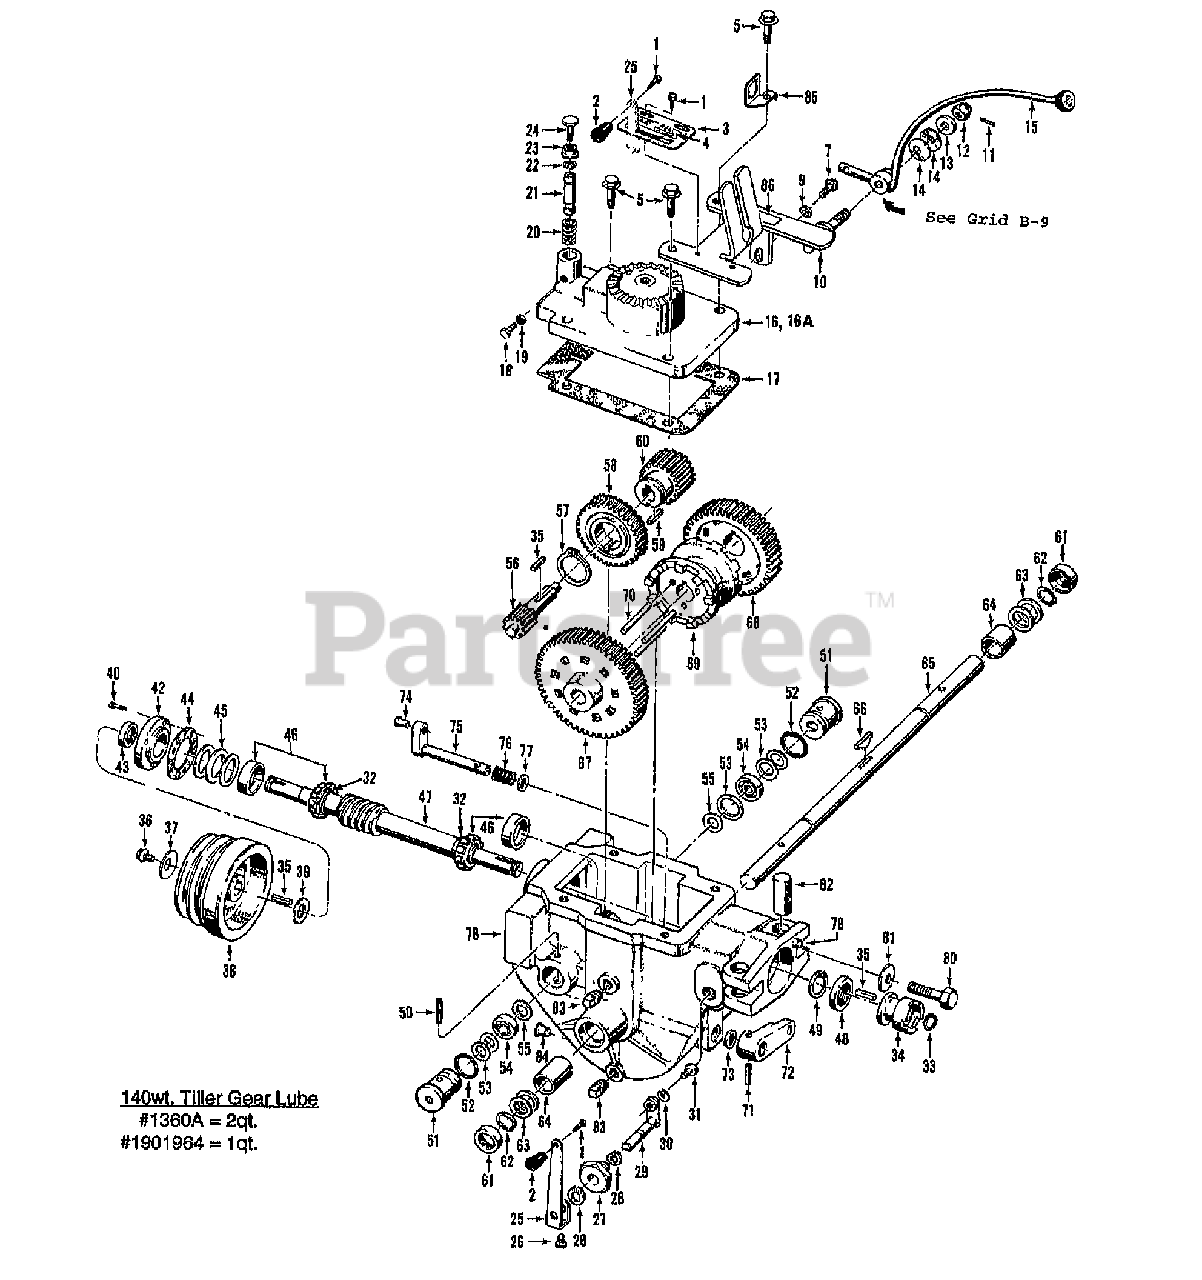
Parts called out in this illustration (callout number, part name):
1	SCR 10-32
2	KNOB-TAPERED
3	PLATE-TINE ENGAGE W/DECAL
4	DECAL-TINE ENGAGE
5	SCR-HFLK 3/8-16X1.50
6	THIS REF. NO. NOT USED
7	SCR-HFLK 5/16-18X.75 ZP
8	THIS REF. NO. NOT USED
9	WASHER-FLAT 5/16 SAE
10	BRKT-H HOOD 2149
11	PIN-SPRING .125 X 1
12	NUT-HEX 1/2-20
13	WASHER-# SHOULDER ZP
14	WASHER-# 1.97X1X.118
15	THIS REF. NO. NOT USED
16	COVER-TRANS RED 2523
16A	ASSM-TRANS COVER OPC
17	GASKET-TRANS COVER
18	SCR-HH 5/16-18X1.0 G5 ZP
19	NUT-HEX 5/16-18 ZP
20	SPRING-REV PLUNGER ZP
21	ASSM-NEUTRAL PLUNGER
22	RING-KLIP EXT .594 ID ZP
23	NUT-HFLK 3/8-16 ZP
24	SCR 3/8-16X1.5 UNC-2AG
25	LEVER-ECCENTRIC RED
26	SCR-HH 1/4-20X.5 GR5 YEL
27	BUSHING-.87X.5X.62 ECC
28	RING-RETAINING 5100-50
29	SHAFT-WELD ECCENTRIC
30	WASHER-LK .25 HI-COLLAR
31	SCR-HXSKT 1/4-20X.38 G8
32	SHIM-1.0X.7656X.062
33	RING-RETAIN EXT .707 ID
34	KIT-CLUTCH DOGS TILLER
34	CLUTCH-DOG HORSE TRANS
35	KEY-.188 SQX1.0
36	SCR-HH 5/16-24X.75 G5 ZP
37	WASHER-.827X.331X.098
38	PULLEY-TRANS MACH
39	WASHER-SHLDR HARDENED
40	SCR-HFLK 1/4-20X.75 G5 ZP
41	THIS REF. NO. NOT USED
42	COVER-FRONT
43	SEAL-PINION SHAFT PT/85030/00
44	GASKET-BRG COVER
45	SHIM-1.75X1.5X.01
45	SHIM-1.75X1.5X.03
45	SHIM-1.75X1.5X.005
45	SHIM-1.75X1.5X.062
46	KIT-BRG CONE&RACE-DRIVESHAFT
47	KIT-WHEELDRIVE ROLL/WORM
48	SEAL-OIL DRIVESHAFT
49	RING-RETAINING 5000-181
50	PIN-SPIROL .25 X 2.0
51	PLUG-PINION BRG W/RING
52	RING-O 1 ID
53	SHIM-1.234X1.015X.033
53	SHIM-1.234X1.015X.062
53	SHIM-1.234X1.015X.01
54	BRG-BALL (7 BALLS)
55	WASHER-# 1X.484X.06
56	GEAR-SPLINE 10 TEETH MACH
57	RING-RETAINING 5100-150
58	GEAR-WORM MACH
59	KEY
60	GEAR-SPUR 20 TEETH MACH
61	SEAL-OIL WHEELSHAFT
62	RING-HEAVY EXT .906 ID
63	SHIM-1.375X1.015X.062
63	SHIM-1.375X1.015X.03
63	SHIM-1.375X1.015X.015
63	SHIM-1.375X1.015X.01
63	SHIM-1.375X1.015X.005
64	BUSHING-1.25X1.005X1.5
65	KIT-WHEELSHAFT
66	KEY-HI PRO .25X1.812
67	GEAR-SPUR 56 TEETH MACH
68	GEAR-SPUR 46 TEETH MACH
69	CLUTCH-MACH
70	PIN-CLUTCH .25 2.65
71	PIN-SPIROL .188 X 1.25
72	LEVER-ECC. #1029
73	SEAL-OIL ECCENTRIC
74	PIN-.375 X .72
75	SHAFT-ECCENTRIC HORSE TLR
76	SPRING .845 X 1.25
77	WASHER # .875 X .65 X .06
78	CASE-TRANS W/PIN
79	PIN-DRIVE .375X.75 ZP
80	SCR-HH 1/2-13X2.0 G5 ZP
81	WASHER-DISC SPRING
82	POST (TC)
83	PLUG-PIPE 1/4 NPT
84	PLUG-CAP (RED)
85	CLIP-CONNECTOR
86	DECAL-FWD INTERLOCK WIRE
